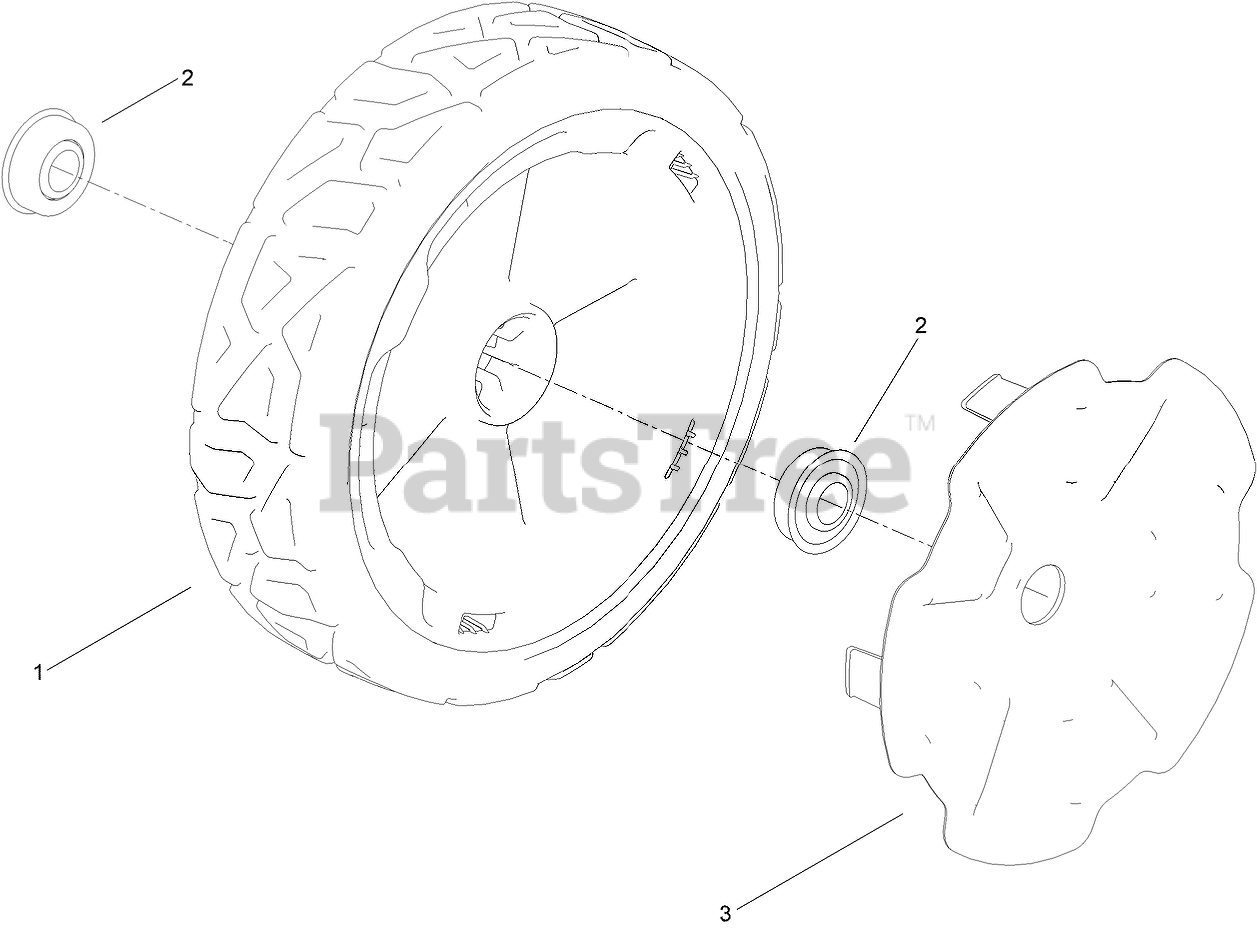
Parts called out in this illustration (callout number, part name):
1	WHEEL-TORO REAR
2	BEARING
3	REAR WHEEL TRIM - TORO
